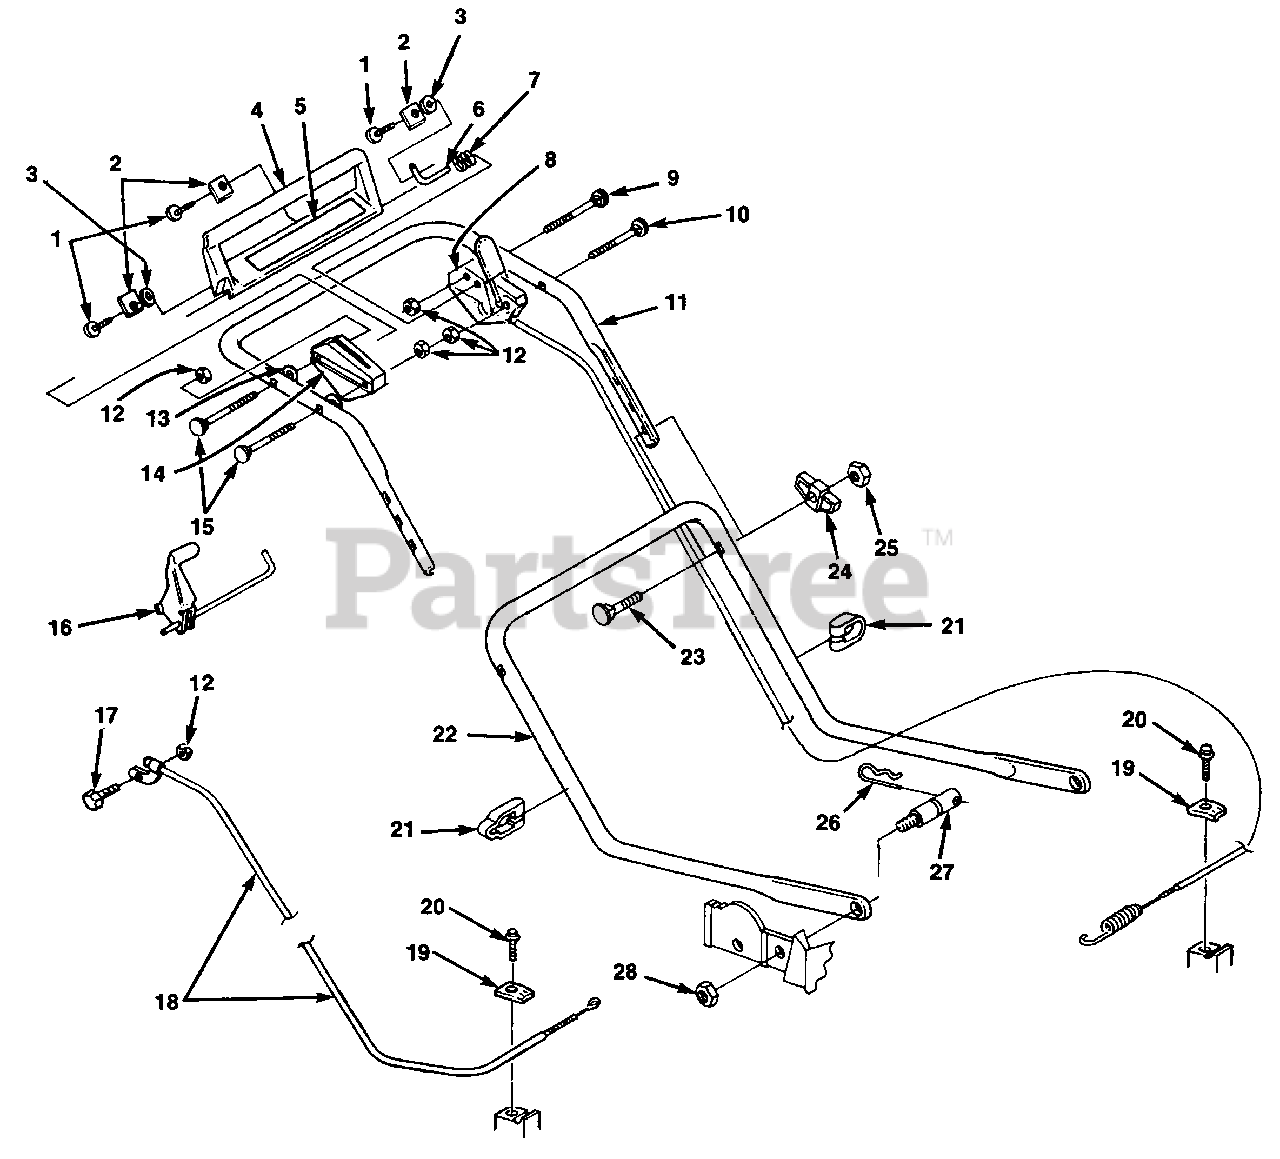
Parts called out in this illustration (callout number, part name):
1	SCREW- (1/4-10 x 5/8")
2	CLAMP- Pivot shaft
3	WASHER- Plain (1/4")
4	BAIL- Brake control
5	DECAL- Brake bail
6	SHAFT- Pivot
7	SPRING- Compression
8	CONTROL- Blade/Brake/Clutch
9	BOLT- Sq. neck (1/4-20 x 2 1/8")
10	BOLT- Sq. neck (1/4-20 x 2 1/4")
11	HANDLE- Upper
12	NUT- Hex (1/4-20)
14	BOX- Pivot
15	BOLT- Sq. neck (1/4-20 x 2")
16	LEVER- Traction
17	SCREW- (1/4-20 x 1 1/2")
18	CABLE- Traction
20	SCREW- (1/4-20 x 5/8")
21	TIE- Cable
22	HANDLE- Lower
23	BOLT- Handle joining
24	KNOB- Handle
25	NUT- Hex (5/16 x 18)
26	PIN- Cotter hair
27	STUD- Handle mtg.
28	NUT- Flange (5/16-18)
